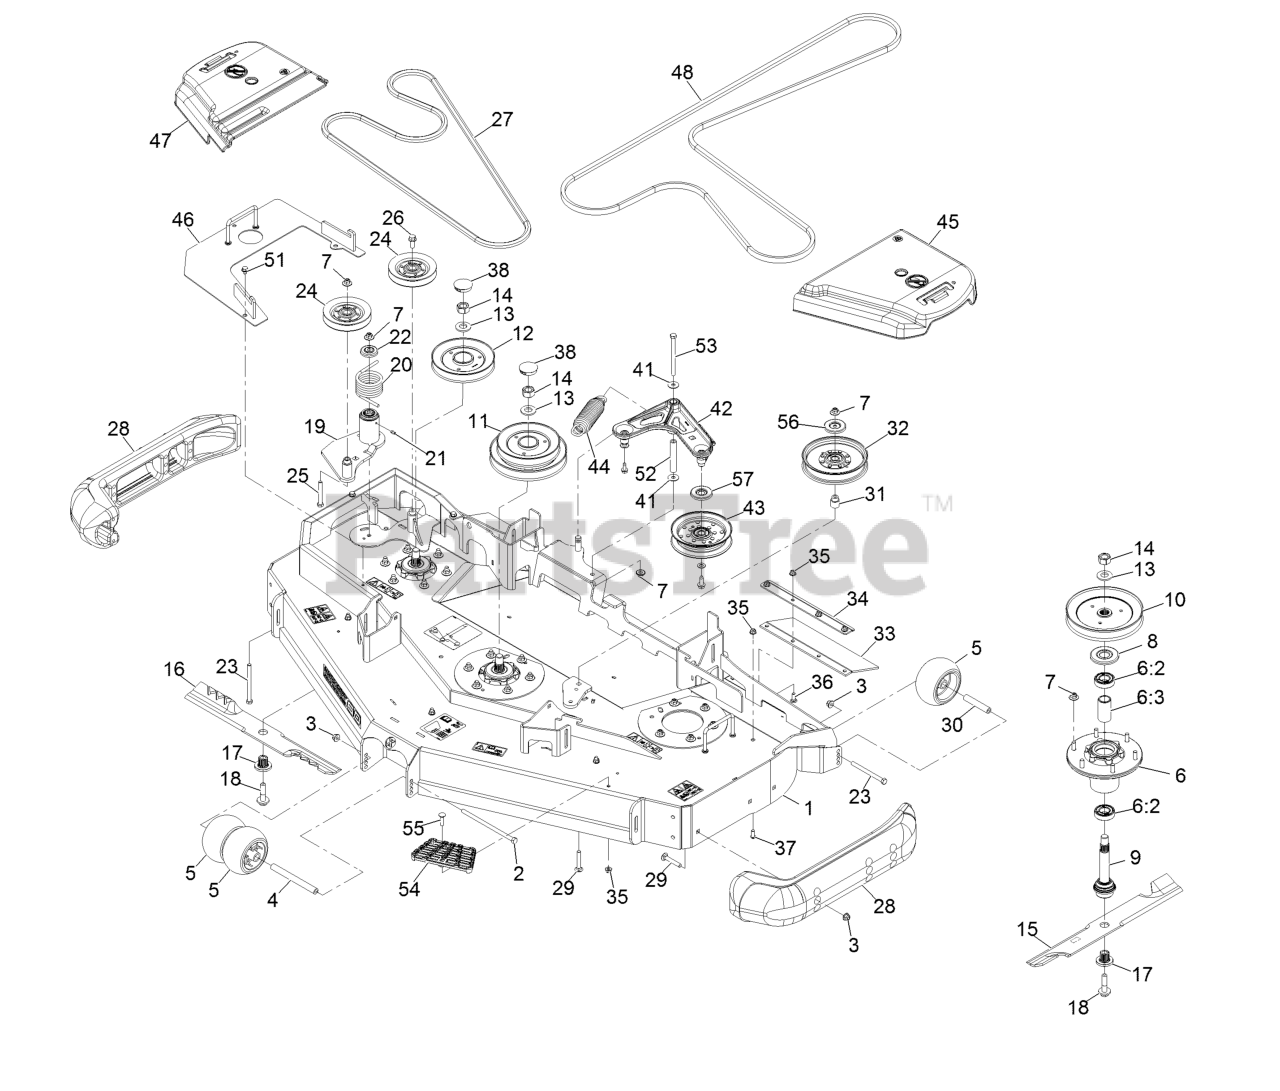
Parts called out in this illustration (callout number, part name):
1	ASM-Deck W/Decals 60Rd
2	Screw-HH 3/8-16 X 7 3/8
3	Nut-Nyloc 3/8-16 Flg
4	Spacer-Wheel
5	Roller-Scalp, Anti
6	ASM-Cutter Hsg With Bearings
6:2	Bearing-Ball
6:3	Spacer-Bearing
7	Nut-Nyloc 3/8-16 Flg
8	Guard,Bearing Top .989
9	ASM-Spindle And Seal
10	Sheave,Blade Drive 7.25
11	Sheave, Double 60Rd
12	Sheave-Rd Rev Drive Series 4
13	Washer-Spring Disc 3/4
14	Nut-Hex
15	Blade, Notched
15	Blade, Low Lift
15	Blade-Extreme 2, 20.50"
16	Blade-Low Lift 20.5, Rd60
16	Blade-Extreme 2-20.50, Rd60
17	Bushing, Splined
18	Screw-Sems 1/2-20 X 2.19
19	Idler ASM
20	Spring-Torsion
21	Zerk-1/4-28 Str
22	Guard-Top
23	Screw-HH 3/8-16 X 4-1/2
25	Screw-HH 3/8-16 X 2 3/4
26	Screw-HH Flg 3/8-16 X 1
27	Belt
28	Skid-Bumper, Deck
29	Bolt-Carriage 3/8-16 X 2 1/
30	Tube-Spanner
31	Bushing, Idler
32	Idler-Pulley, Flat 6.00X1.00
33	Guard-Tire
34	Support-Outer Flap
35	Nut-Nyloc 5/16-18 Flg
36	Bolt-Carriage 5/16-18 X 7/8
37	Screw-Button Head 5/16-18 X 3/4
38	Plug,Black Nylon 1.75
42	Idler Arm ASM
43	Idler-Pulley, Flat
44	Spring-Extension
45	Cover-Belt, LH
46	Cover-Drive, Reverse
47	Cover-Belt, RH
48	Belt-V
51	Screw-HWH 5/16 X 1/2 Tf
52	Bushing
53	Screw-HH 3/8-16 X 4 3/4
54	Step-Deck
55	Bolt-Carriage 5/16-18 X 1 1/4
56	Shield-Dust
57	Shield-Guard, Dust
